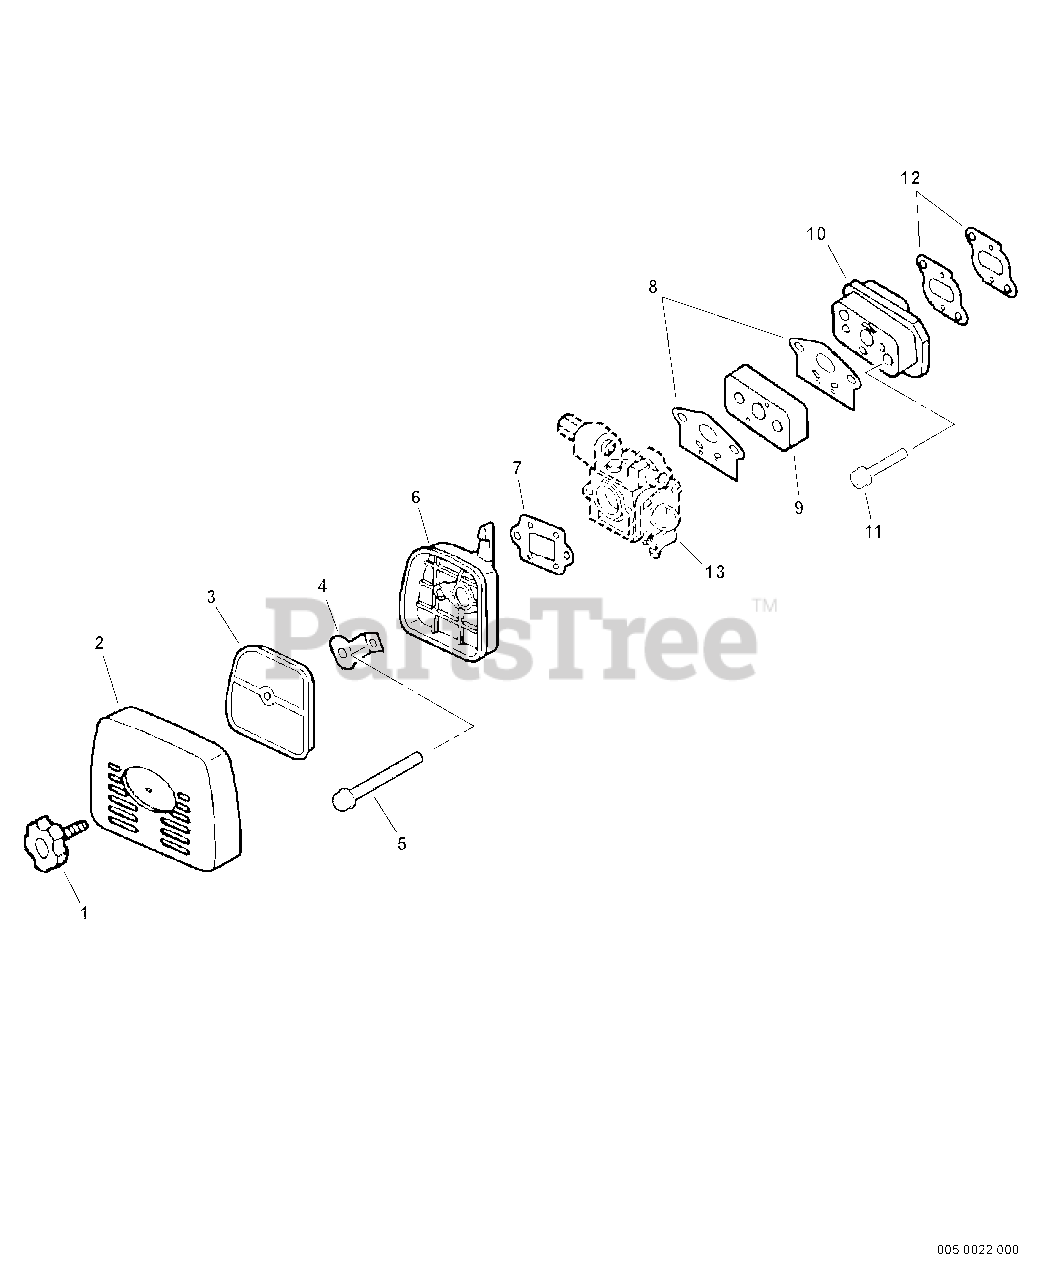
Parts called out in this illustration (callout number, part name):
1	THUMBSCREW
2	COVER, AIR FILTER
3	FILTER, AIR - HEAVY DUTY
4	PLATE, PREVENT
5	SCREW - 5X65
6	CASE, AIR FILTER
8	GASKET, INTAKE
9	INSULATOR, INTAKE
10	INSULATOR, INTAKE
11	SCREW - 5X25
12	GASKET, INTAKE
13	CARBURETOR
